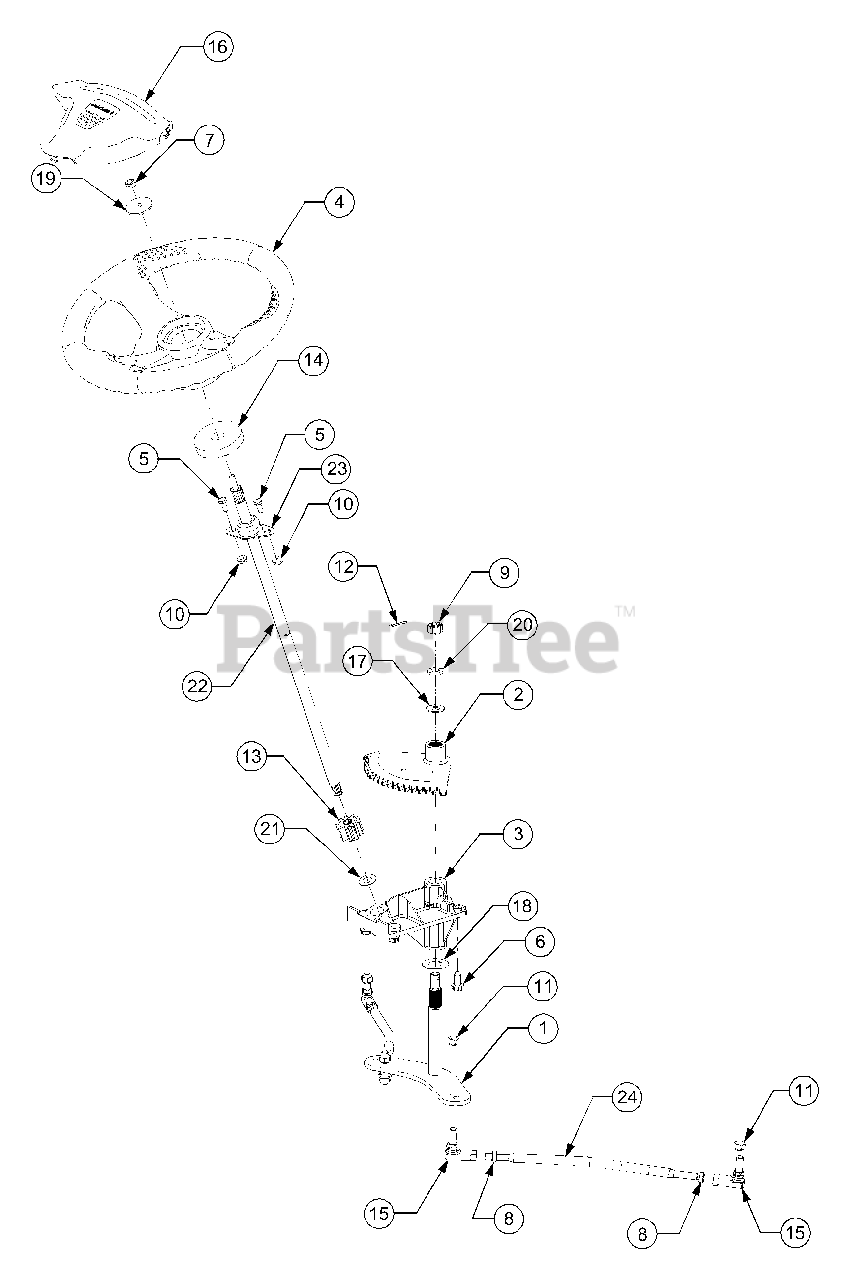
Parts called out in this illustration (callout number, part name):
1	Arm Assy, Lower Steering
2	Segment Assy, 18T Steering
3	Housing Assy,
4	Wheel, Steering, Soft Grip
5	Screw, Hex Cap, 1/4 - 5/16 - 18 x .75, GR5
6	Screw, Hex Wash. Hd. Tapp 5/16 - 18 x .75
7	Nut, Hex Center Lock, 5/16-18
8	Nut, Hex Jam, 3/8-24 GR2
9	Nut, Hex Slotted, 1/2-20 GR5
10	Nut, Hex Flange Lock, 5/16 - 18
11	Nut, Hex Lock, 3/8-24 GR5
12	Pin, Cotter, 3/32 Dia x 1.25
13	Pinion, Steering
14	Gasket, Steering
15	Joint, Ball, 3/8-24
16	Cover, Steering Wheel
17	Washer, Flat, .510 x 1 x .06 Thk
18	Washer, Flat, .760 x 1.5 x .03 Thk
19	Washer, Flat, Bell
20	Washer, Lock, 1/2
21	Washer, Flat, .531 x 1 x .027 Thk
22	Shaft, Steering
23	Bearing, Flange
